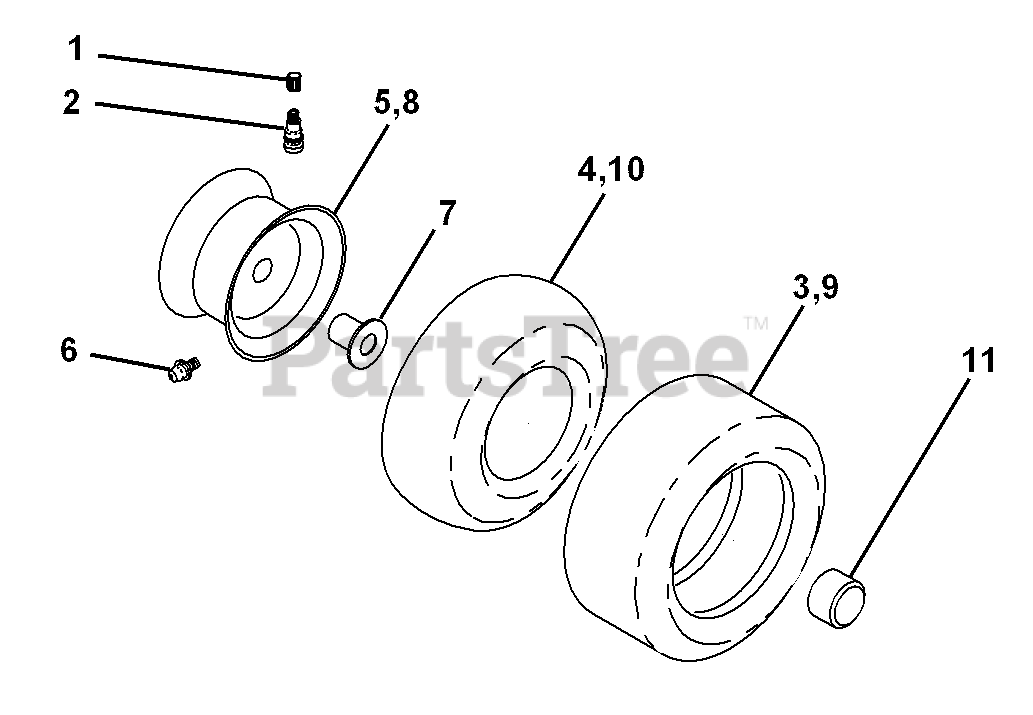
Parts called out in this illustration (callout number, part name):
1	Cap Valve Tire
2	Stem Valve
3	Tire F Ts 15 X 6 0 - 6 Service
4	Tube Front
5	Rim Asm 6"front Silver Service
6	Fitting Grease
7	Bearing Flange
8	Rim Asm 8"rear Silver Service
9	Tire R Ts 20x10-8 C Service
10	Tube Rear
11	Cap Axle Blk 1 50 X 1 00
11	Sealant, Tire
